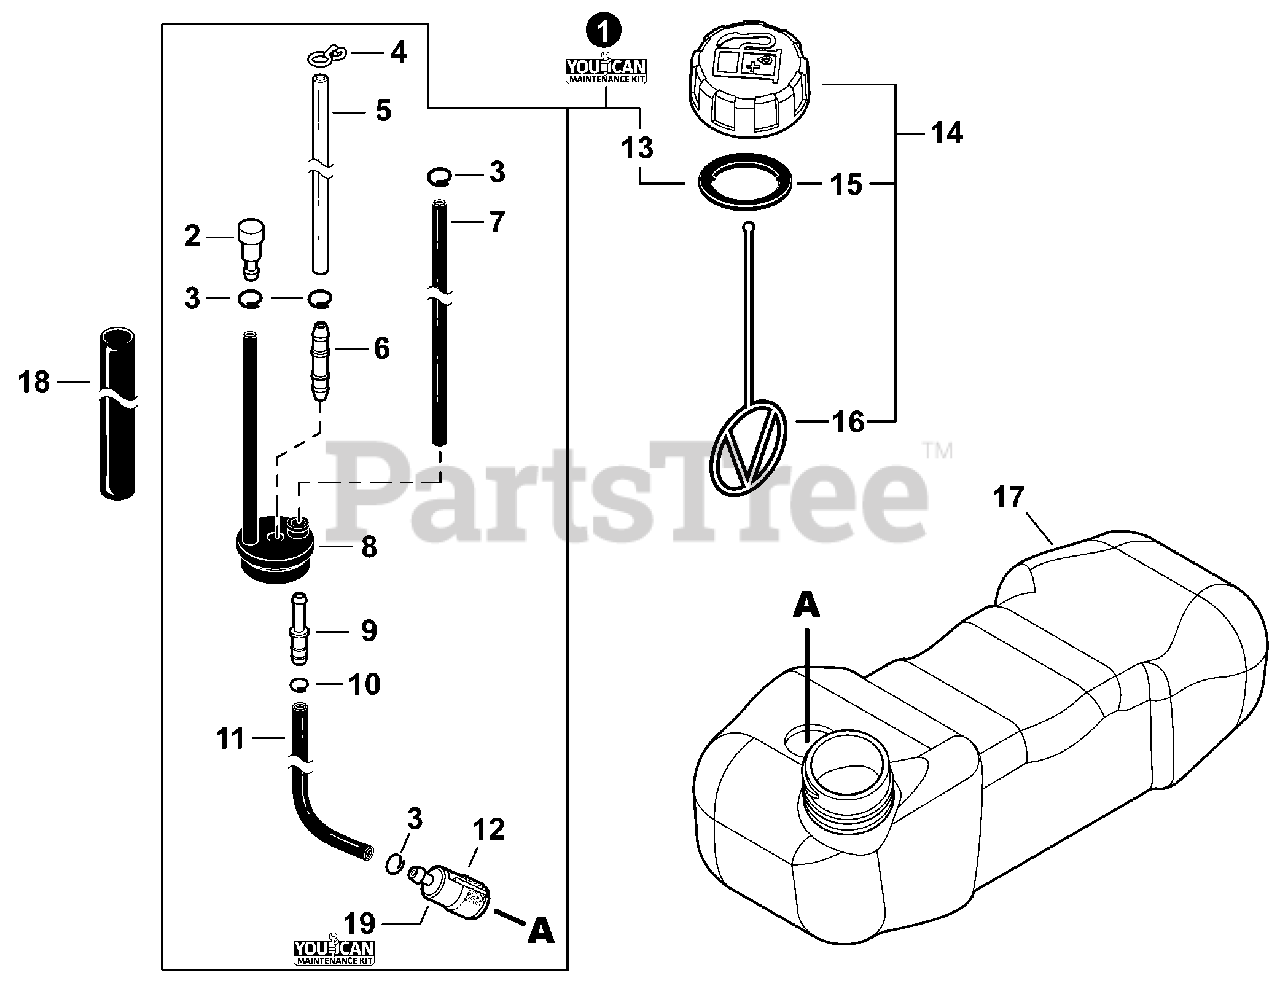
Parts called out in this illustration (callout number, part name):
1	FUEL SYSTEM KIT - YOUCANT
2	VENT ASSY
3	CLIP Ø6
4	CLIP, SPRING Ø5.2
5	PIPE, FUEL 3×6×133 CLEAR
6	CONNECTOR, PIPE
7	PIPE, FUEL 3×5×145 BLACK
8	GROMMET, FUEL W/VENT PIPE
9	CONNECTOR, PIPE Ø5ר3.5
10	CLIP Ø6.5 MM
11	PIPE, FUEL 3.3×6×195 BLACK
12	FILTER, FUEL
13	GASKET, FUEL CAP
14	CAP ASSY, FUEL
15	GASKET, FUEL CAP
16	CONNECTOR, CAP L= 100 MM
17	TANK, FUEL
18	TUBE, PROTECTIVE
19	TUNE-UP KIT - YOUCANT
